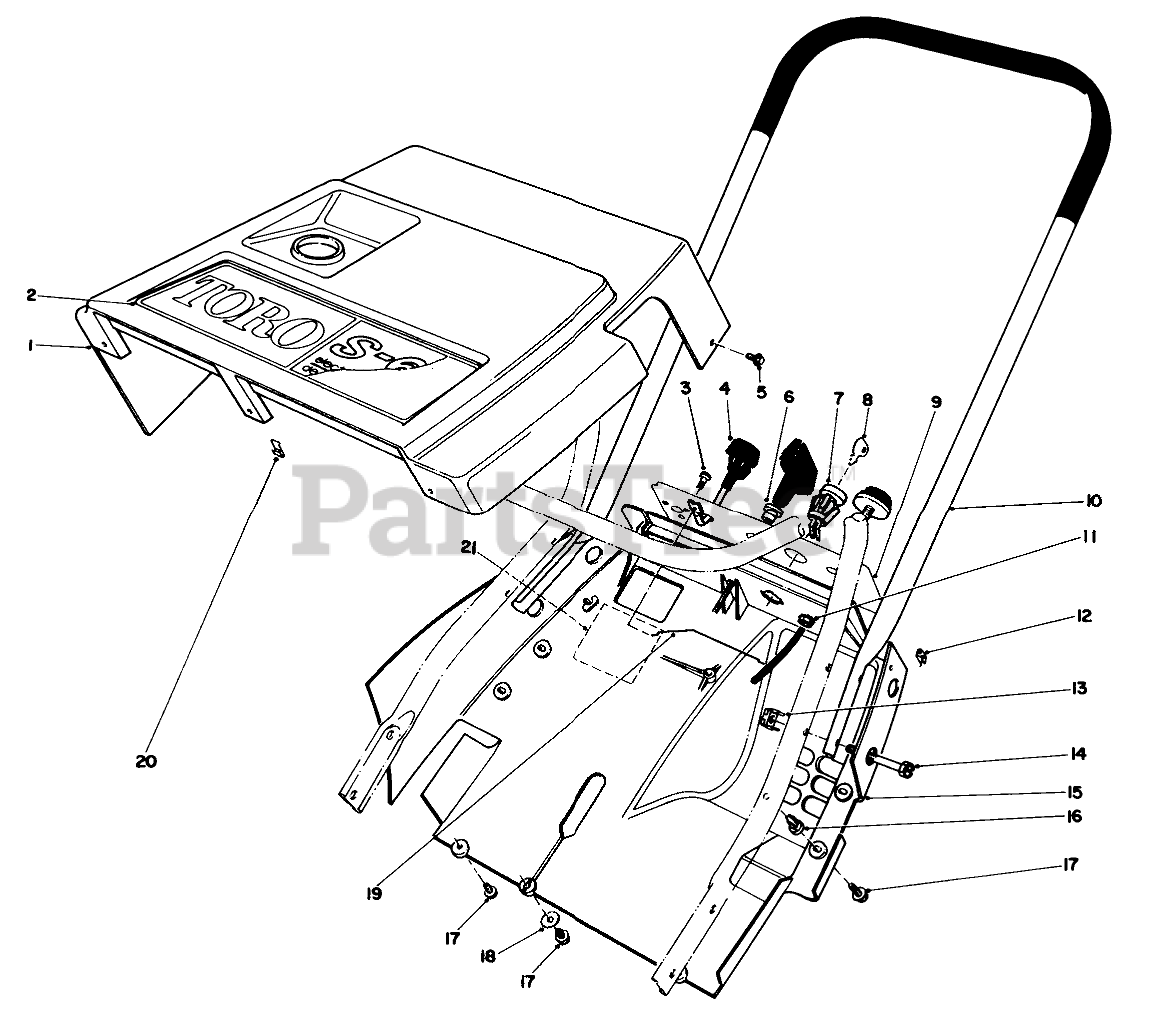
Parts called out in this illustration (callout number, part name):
1	Shroud-Upper
2	TORO DECAL
3	SCREW-PLASTITE
4	CHOKE CONTROL ASM
5	SCREW-HWHTF
6	GUIDE-ROPE, STARTER
7	SWITCH
8	KEY-IGNITION
9	Decal-Control Panel
10	Handle-Upper
11	NUT-KEPS
13	TINNERMAN NUT
14	SCREW-HEX HD SLOT
15	LOWER SHROUD
16	Nut-Push
17	SCREW-HWHTF
18	WASHER-FLAT
19	CONTROL WIRE
20	NUT "U"
21	DECAL - CSA
